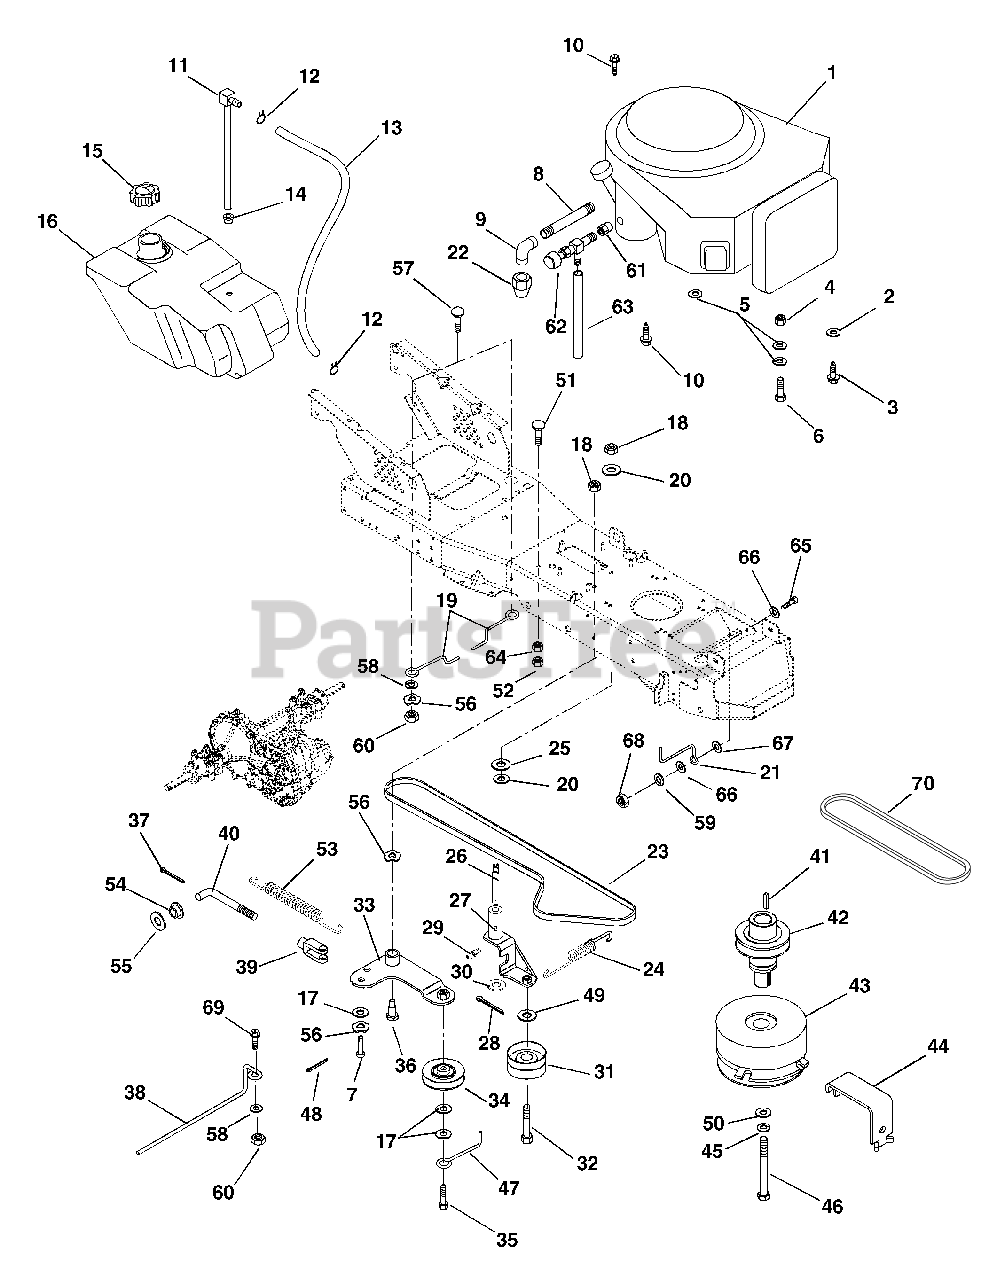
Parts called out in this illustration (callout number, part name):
1	ENGINE,INTEK 31CI VERT NO MFLR
1	ENGINE,INTEK 25HP OHV TWIN
2	@WSHR-LK-EXT.391X.628X.036YWZC
3	@SCR-TAP .38-16X1.25 HWH TR YZ
4	@NUT-LK-TOP-FLG .31-18 YWZC
5	WSHR-FL-STL .328X.875X.062YWZC
6	@BLT-HEX .31-18X1.50 GR5 YWZC
7	PIN-CLEV .31X.937 FLHD YWZC
8	NIPPLE
9	ELBOW .375-18 NPTF
10	@SCR-TAP .31-18X.75 HWH TR YWZ
11	TANK FITTING
12	CLAMP-HOSE WIR.490/.510X.092#8
13	HOSE- FUEL LINE 36.00"
13	HOSE- FUEL LINE 48.00"
14	BSHG-FLG .375 X 1.062 X .625 R
15	FUEL CAP
16	FUEL TANK
17	WSHR-FL-STL .390X.75X.125 YWZC
18	@NUT-LK-TOP-FLG .38-16 YWZC
19	FINGER, BELT
20	WSHR-FL-STL .380X1.50X.125YWZC
21	BELT FINGER
22	ADAPTER, OIL DRAIN
23	V-BELT, 4L-WRAPPED
23	V-BELT, HA-RAW EDGE
24	SPRING, EXT
25	WSHR-FL-STL .469X2.00X.25 YWZC
26	SHOULDER STUD
27	ARM, IDLER PIVOT
28	@PIN-CTR .18X1.25 EXTPRSQCT YZ
29	FTG-LUBE .25-28X.256 YWZC
30	WSHR-FL-STL .505X.880X.072 YWZ
31	IDLER 2.75X1.25
32	@BLT-HEX .38-16X2.75 GR5 YWZC
32	@BLT-HEX .38-16X3.50 GR5 YWZC
33	IDLER PIVOT ARM
34	IDLER-V 3X.38
35	@BLT-HEX .38-16X1.75 GR5 YWZC
35	@BLT-HEX .38-16X2.25 GR5 YWZC
36	BLT-SHLDR .38-16X1.25
37	@PIN-CTR .09X.75 EXTPRSQCT YWZ
38	FINGER, BELT
39	YOKE, .312-24 X 2.25
41	KEY-SQ .25 X 1.25 X .25 SAE
42	SHEAVE EXT., SHAFT (HYDRO)
42	SHEAVE EXTENSION SHAFT- HYDRO
43	ELECTRIC CLUTCH/BRAKE (3.4AMP)
43	CLUTCH, ELECTRIC - WARNER
44	ANCHOR, CLUTCH
44	ANCHOR - CLUTCH
45	WSHR-LK .438X.133 HVY YWZC
46	BLT-HEX .44-20 X 5 GR5
46	BLT-HEX .44-20X4.00 GR5 YWZC
47	FINGER - BELT
48	PIN-HAIR INT .08X.18X1.18 YWZC
49	WSHR-FL-STL .390X.88X.18 YWZC
50	WSHR-FL-STL.463X1.375X.25 YWZC
51	BLT-RDHDSQNK .31-18X1.0 SHTYZ
52	@NUT-LK-TOP-FLG .31-18 YWZC
53	SG-TENS .105X.85X5.00 WLD 40
54	BSHG-FLG .320X.620X.312 NY
55	WSHR-FL-STL .505X.880X.072 YWZ
56	WAVE WASHER .531X.781X.125FH
57	BLT-RDHDSQSHK.31-18X.75 GR2 YW
58	@WSHR-FL-STL.344X.688X.065YWZC
59	WSHR-LK .312X.097 HVY YWZC
60	@NUT-HEX .31-18 YWZC
61	ADAPTER, OIL DRAIN
62	COCK, OIL DRAIN
63	TUBE OIL DRAIN
64	NUT-LK-NYL.312-18 PL
65	@BLT-HEX .31-18X1.00 GR5 YWZC
66	WSHR-FL-STL .328X1.0X.094 YWZC
67	WSHR-FL-NYL .390X1.000X.062
68	@NUT-HEX .31-18 YWZC
69	BLT-RDHDSQSHK.31-18X.75 GR2 YW
70	V-BELT, HA-RAW EDGE
